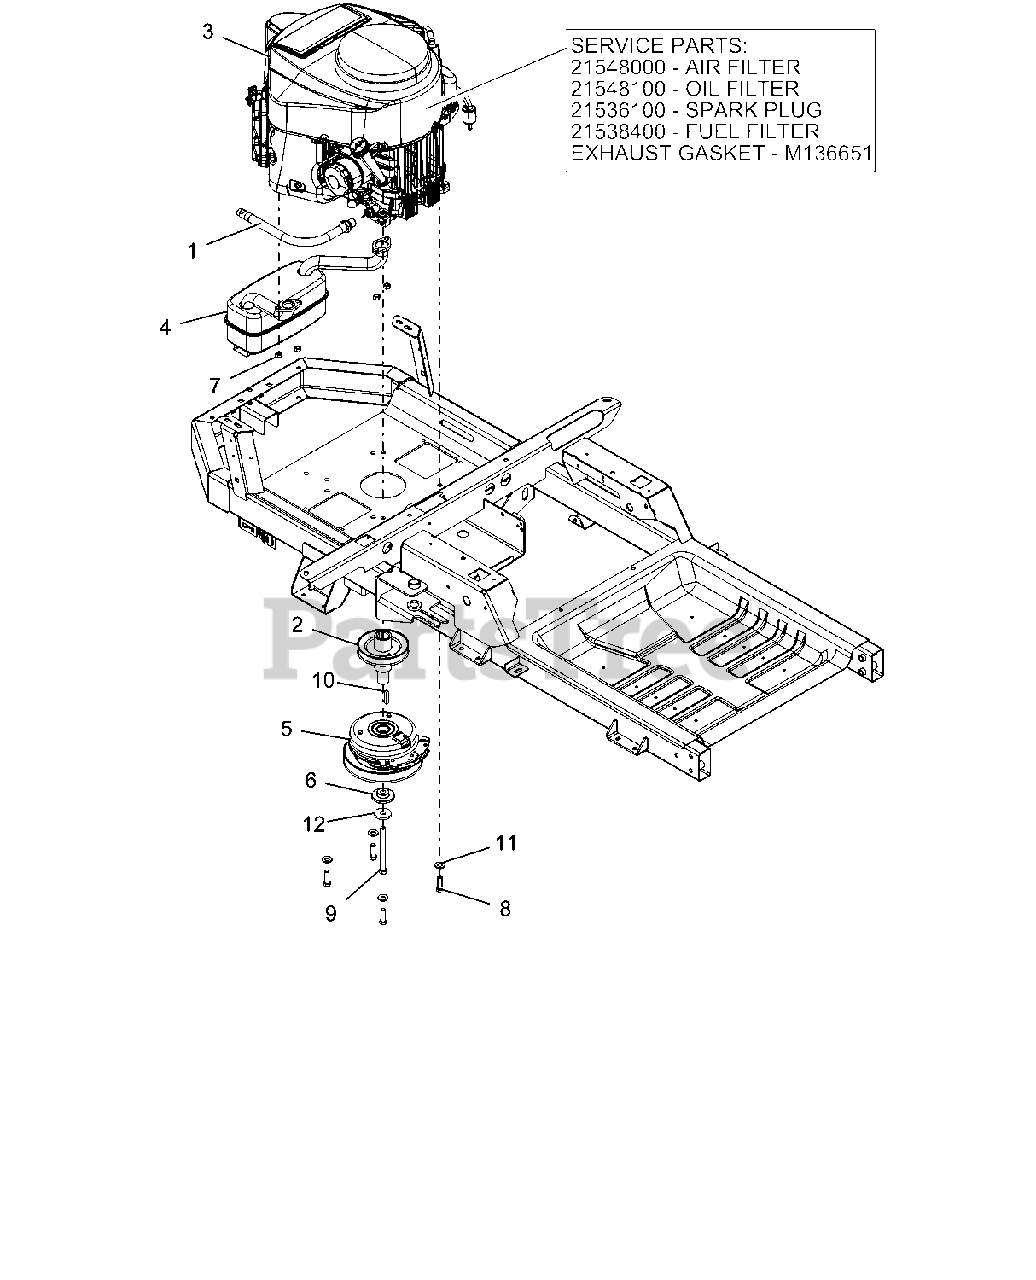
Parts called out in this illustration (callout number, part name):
1	HOSE, OIL DRAIN
2	WLDMT, DRIVE SHEAVE-X
3	FUEL FILTER - KAWASAKI
3	PLUG, SPARK
3	ENGINE, KAWASAKI FR651V 22HP
3	AIR FILTER, KAWASAKI FR
3	OIL FILTER, KAWASAKI FR
3	GASKET, MUFFLER #
4	MUFFLER, KAW
5	CLUTCH,105FTLB MONOPOLE 6.83"
6	BSHG-FLG .469X1.06X.574X2.0
7	NUT-LK-TOP M8-1.25 YWZC
8	BLT-HEX.38-16X1.25 G5YZ NYTORQ
9	BLT-HEX.438-20X4.5GR8YZ NYTORQ
10	KEY-SQ .25 X 1.25 X .25 SAE
11	WASHER, 3/8" SPRING DISC
12	WASHER, 7/16" SPRING DISK
